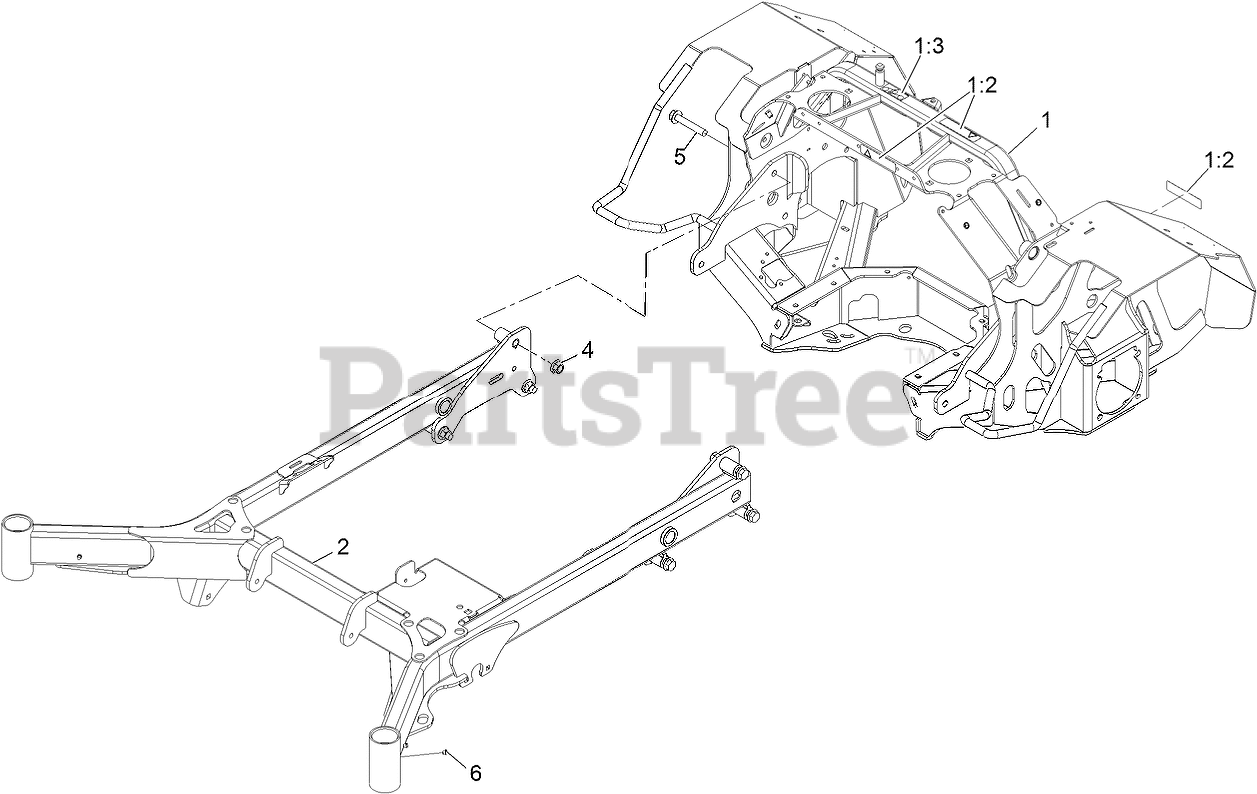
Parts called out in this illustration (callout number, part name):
1	ASM, Rear Frame W/Decals
1:2	DECAL-WARNING
1:3	DECAL-BELT ROUTING HYD
2	Weld, Front Frame, 60
4	Nut-Lock 1/2-13
5	SCREW-HF
